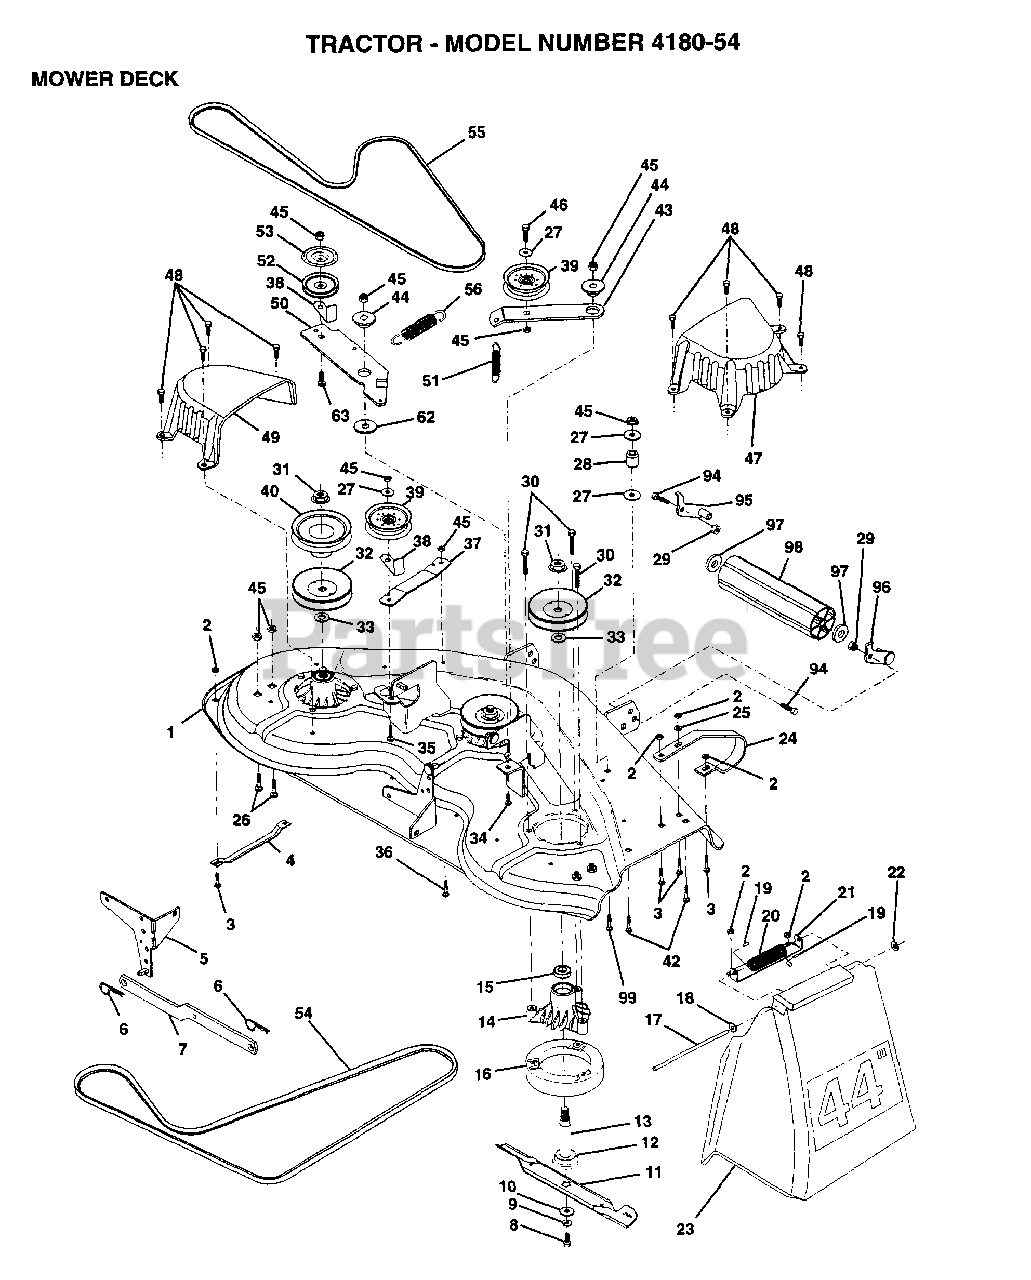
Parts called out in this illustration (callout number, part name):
1	"DECK ASM WELD44"""
4	RUNNER-LH M
5	BRKT.ASM.SW.44/50
8	BLADE BOLT
10	WASHER.HARD.BLADE
11	"BLADE.44"" HIPERF"
12	BEARING.BALL
13	SHAFT.ASM.W/BRNG
14	HOUSING.MAND.44.V
15	BEARING
16	STRIPPER RND MWR
17	ROD-HINGE T
18	WASHER
19	CAP-SLEEVE LT
20	SPRING TORSION
21	BRKT DEFLECTOR
22	NUT PUSH M
23	DEFLECTOR SHIELD
24	RUNNER.RH
25	WASHER M
26	BOLT
27	WASHER
29	NUT
33	WASHER
34	BOLT.3/8-14X1.25
35	BOLT
36	BOLT D
37	STIFFENER.ARM.IDL
39	FLAT IDLER PULLEY
40	"PULLEY.DRIVEN.44"""
42	BOLT
43	"ARM.IDLER.SEC.44"""
44	SPACER RETAINER
47	"COVER.MAND.RH.44"""
48	SCREW.1/4-20X5/8
49	COVER.MANDREL.LH
50	ARM.IDLER.PRIMARY
51	"SPRING.SEC.44""VEN"
52	PULLEY.IDLER.VGRO
53	SHIELD.IDLER.44.V
54	V-BELT.PRIM.78.5.
55	BELT-V.88.12.MW
56	SPRING.EXT.DECK.
62	HARDENED WASHER
63	BOLT.3/8-16X1.50
94	BOLT
97	WASHER
99	BOLT
